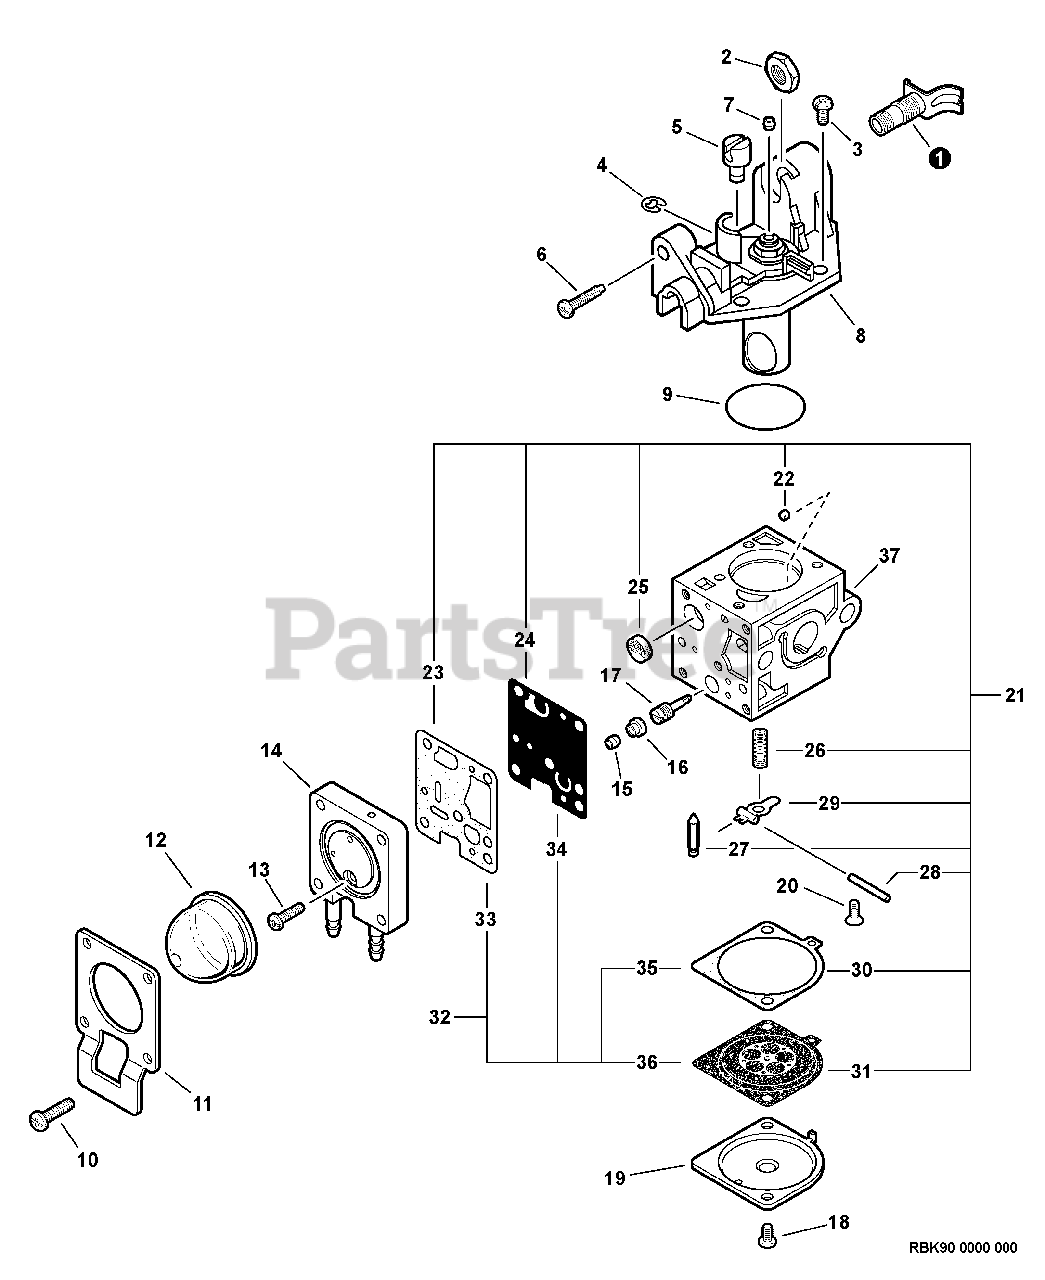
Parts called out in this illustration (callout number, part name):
1	ADJUSTER, CABLE
6	SCREW, IDLE ADJUST
8	COVER ASSY, ROTOR
11	RETAINER, PURGE BULB
12	BULB, PURGE
14	BODY ASSY, PURGE
16	CAP, LIMITER
17	NEEDLE, HIGH SPEED
19	COVER, METERING DIAPHRAGM
21	REPAIR KIT
22	GUIDE, ROLLER
23	GASKET, PUMP
24	DIAPHRAGM, PUMP
25	STRAINER
26	SPRING, METERING LEVER
27	VALVE, INLET NEEDLE
28	PIN, METERING LEVER
29	LEVER, METERING
30	GASKET, METERING
31	DIAPHRAGM, METERING
32	GASKET / DIAPHRAGM KIT
33	GASKET, PUMP
34	DIAPHRAGM, PUMP
35	GASKET, METERING
36	BODY, CARBURETOR
37	DIAPHRAGM, METERING
